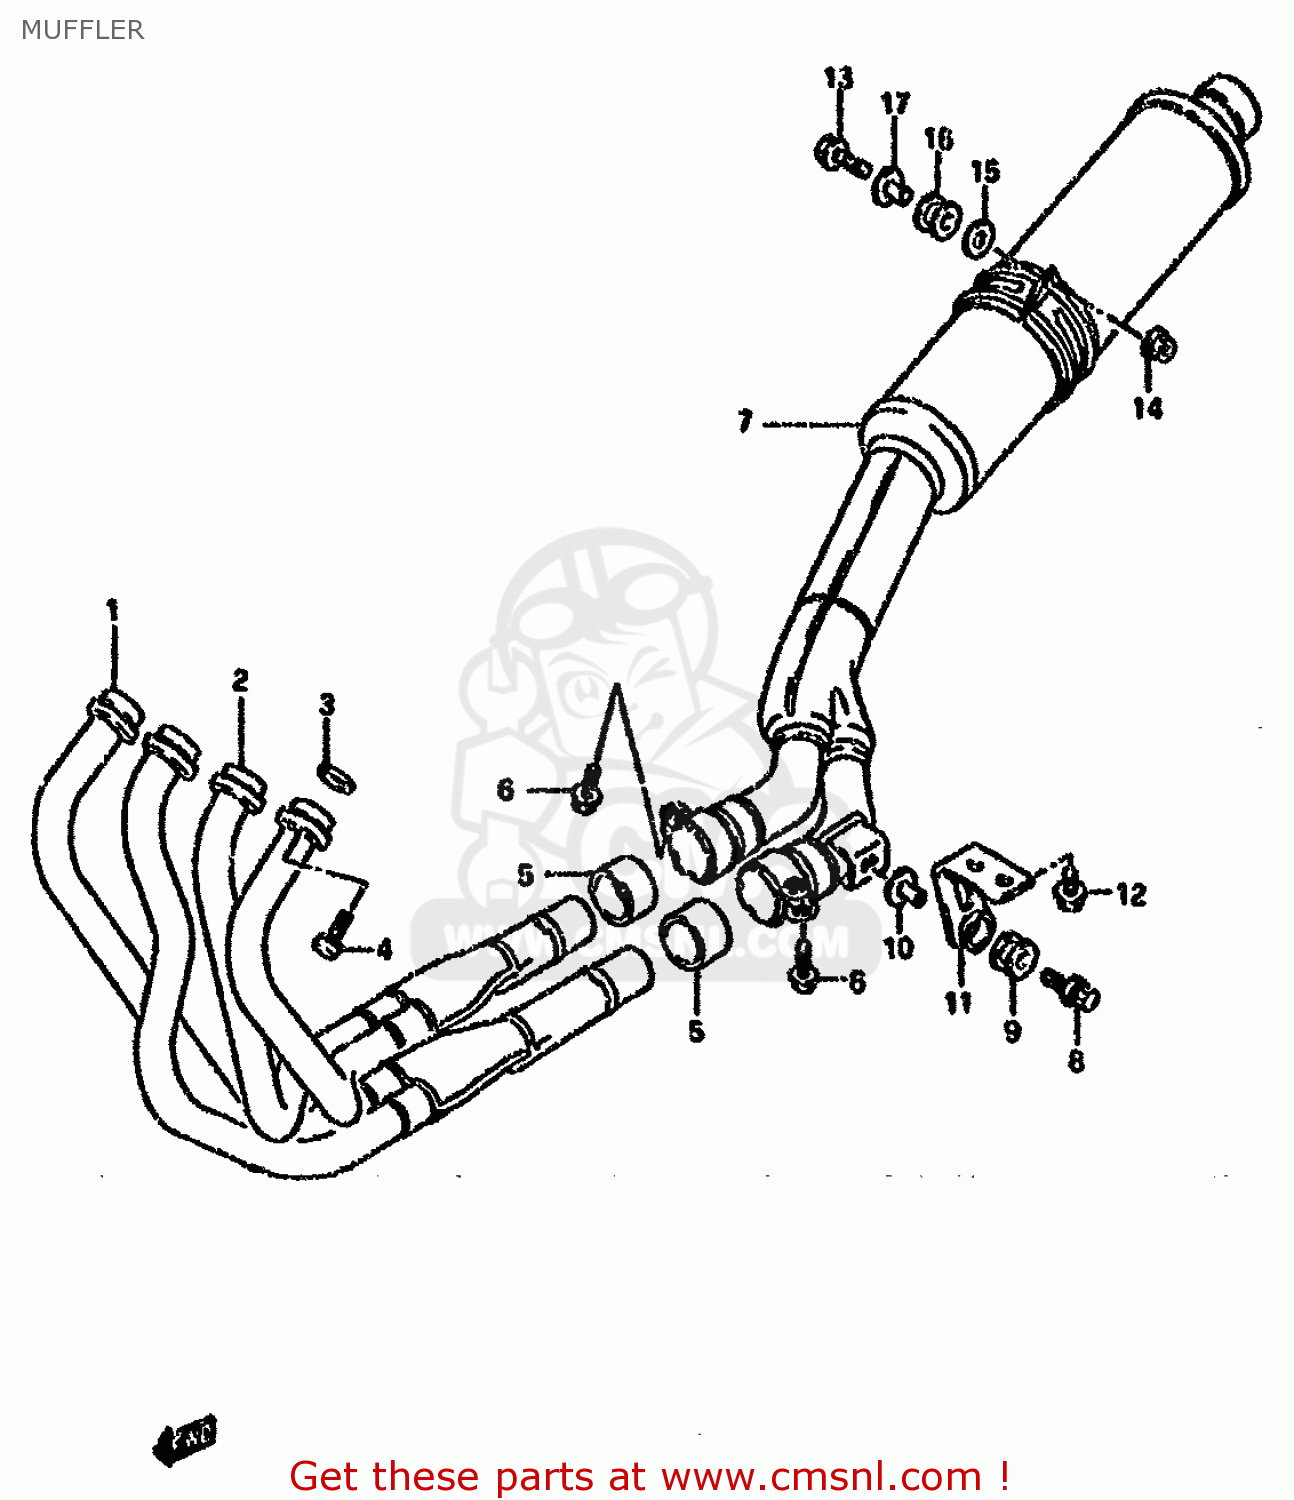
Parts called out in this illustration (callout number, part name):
1	PIPE,EXHAUST RH
2	PIPE,EXHAUST LH
3	GASKET,EXHAUST PIPE
4	BOLT
5	CONNECTOR,MUFFLER
6	BOLT
7	BODY,MUFFLER
8	BOLT 8X40
9	CUSHION
10	SPACER(8.6X12X24.2)
11	DAMPER,MUFFLER SUPPORT,FRONT
12	BOLT
13	BOLT
14	NUT
15	WASHER (8.1X33X1.6)
16	CUSHION
17	SPACER(8.6X12X27.1)
